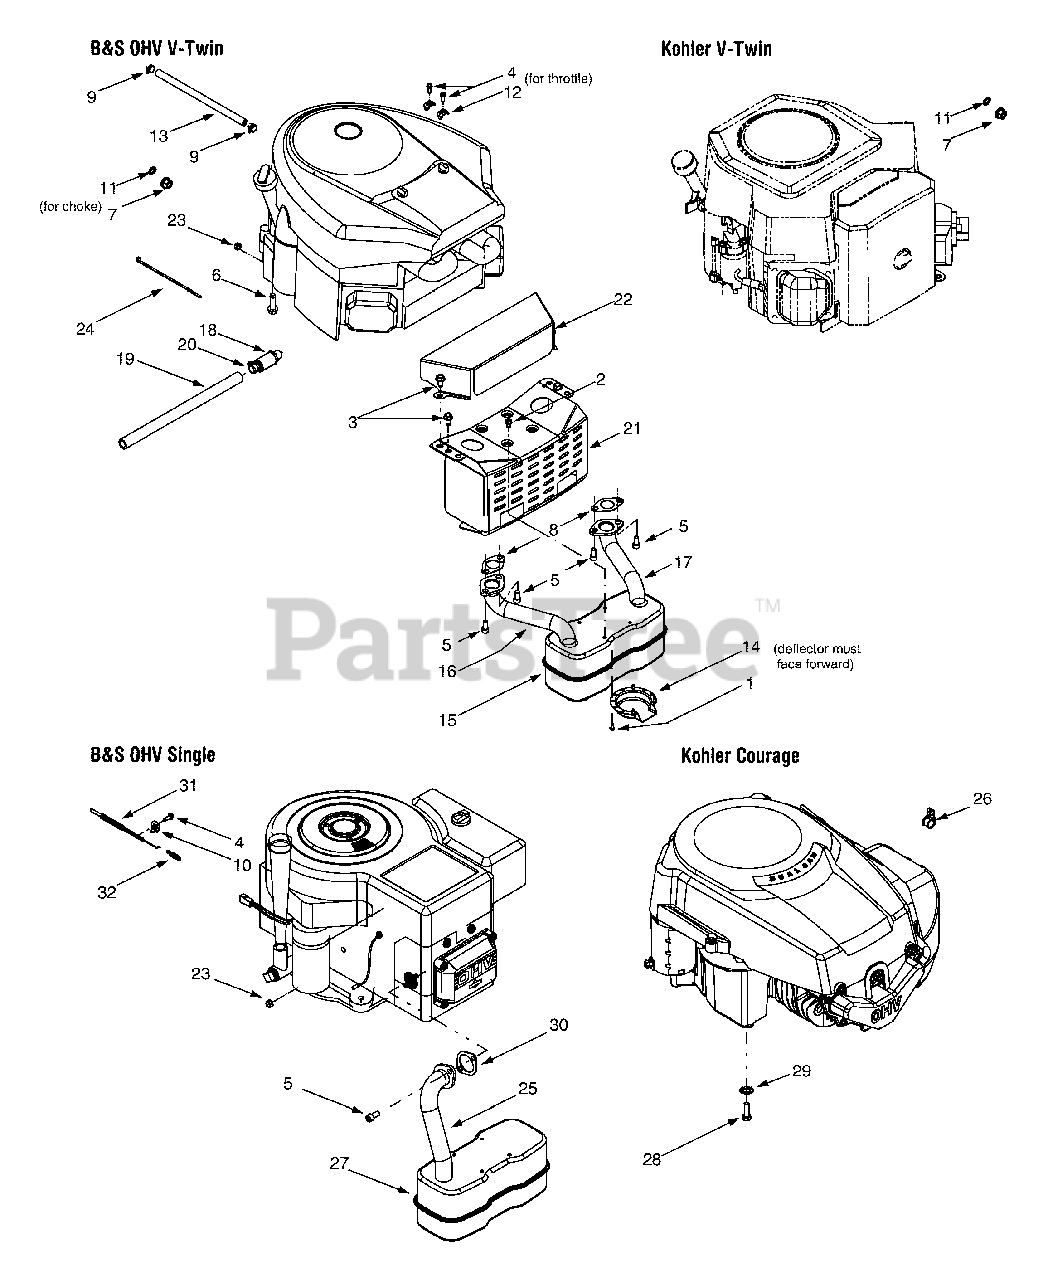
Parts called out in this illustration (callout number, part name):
1	Self-tapping Screw, #8-18 x.50
2	Self-tapping Screw, 1/4-20 x.50
3	Self-tapping Screw, 5/16-18 x.625
4	Screw, #10-32 x.625
5	Screw, 5/16-18 x.625
6	Self-tapping Screw, 3/8-16 x 1.25
7	Hex Nut, 3/8-16
8	Exhaust Gasket
9	Hose Clamp
10	Casing Clamp
11	Lock Washer,.406 x.875 x.059
12	Casing Clamp
13	Fuel Line Hose
14	Muffler Deflector
15	Muffler, Twin Inlet
16	RH Exhaust Pipe
17	LH Exhaust Pipe
18	Oil Drain Valve
19	Oil Drain Hose
20	Oil Drain Cap
22	Engine Heat Shield
23	Hex Sems Nut, 1/4-20
24	Cable Tie
25	Exhaust Pipe
26	Clamp
27	Muffler, Single Inlet
28	Screw, 3/8-16 x 1.00
29	Flat Washer
30	Exhaust Gasket
31	Throttle Cable
32	Extension Spring,.275 x 1.25
